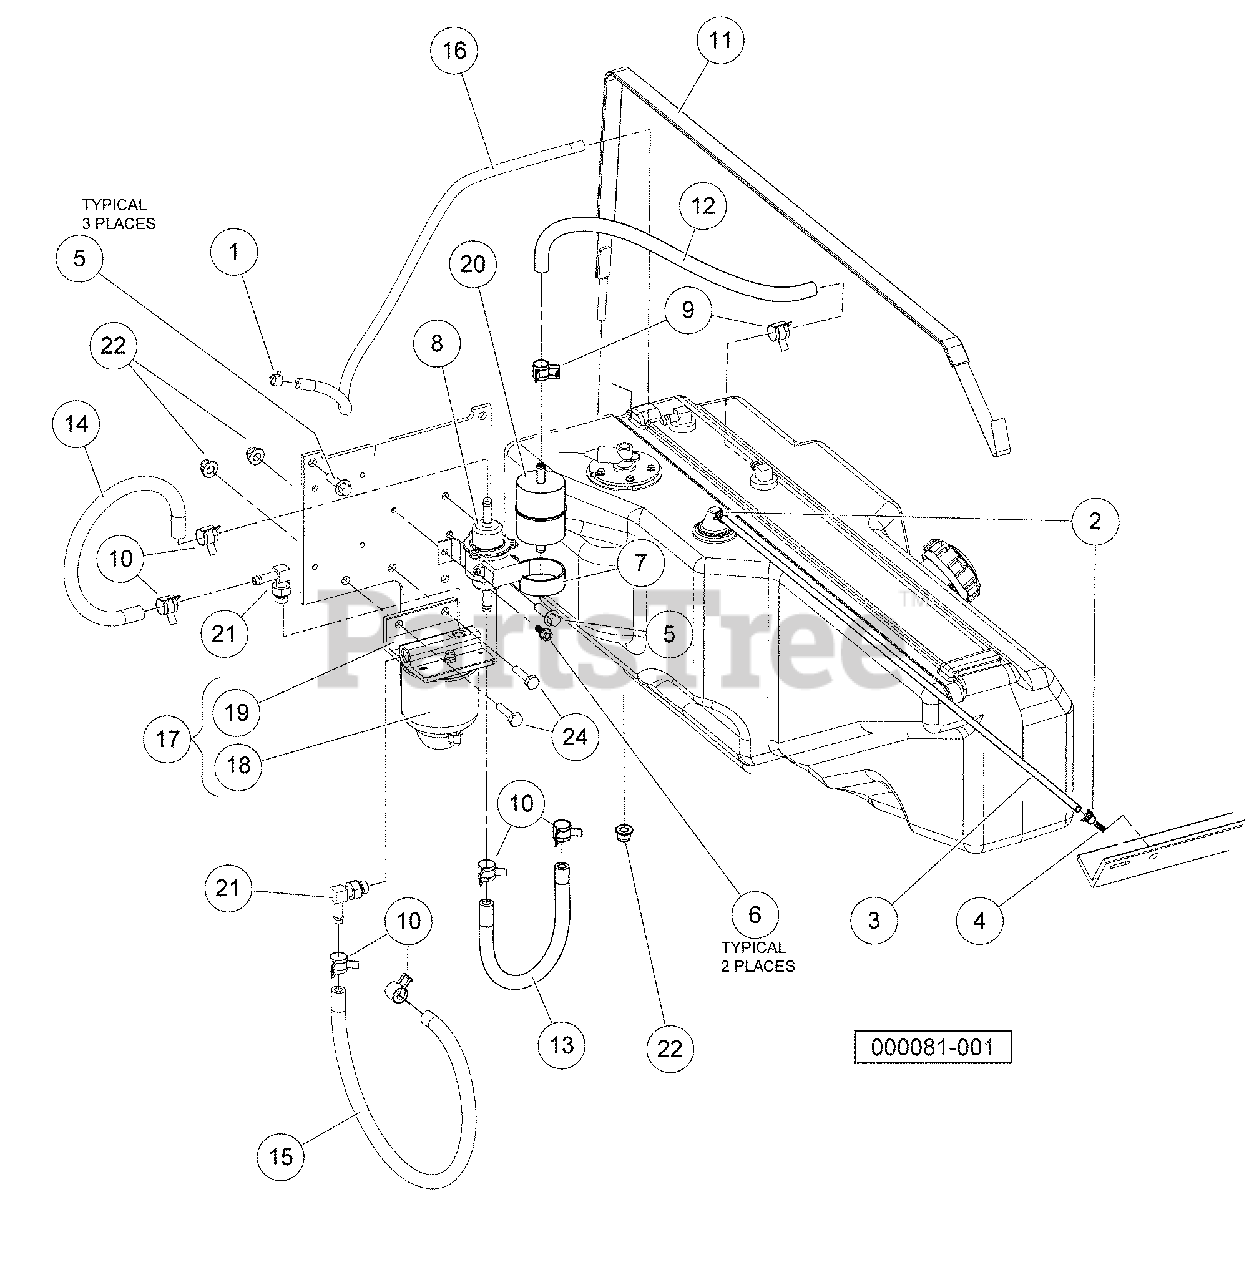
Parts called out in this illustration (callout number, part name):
1	Clamp, Green Hose
2	Clamp, 0.301 ID Hose
3	Hose, Fuel, Vent, 22" Long
5	Screw, M8X1.25X30, Hex
6	Screw, M6 X 16 Tt Hx Fl Hd
7	P-Clamp, Insulated 1.75 In
8	Pump, Diesel Fuel Electric
9	Clamp, Hose, Ctb 13mm
10	Clamp, Hose, Ctb 14mm
11	Strap, Tank, Fuel
12	Hose, Tank To Prefilter Diesel
13	Hose, Fuel Prefilter To Pump
14	Hose, Fuel Pump To Filter
15	Hose, Fuel Filter To Eng
16	Hose, Fuel Return
17	Filter Assy, Fuel
19	Adapter, 90, 5/16 Tube
20	Filter, fuel
21	Plate, Fuel/Oil System
22	Lock nut, Flg M8 x 1.25 Nylon
24	Bolt, M8 x 1.25 x 30
